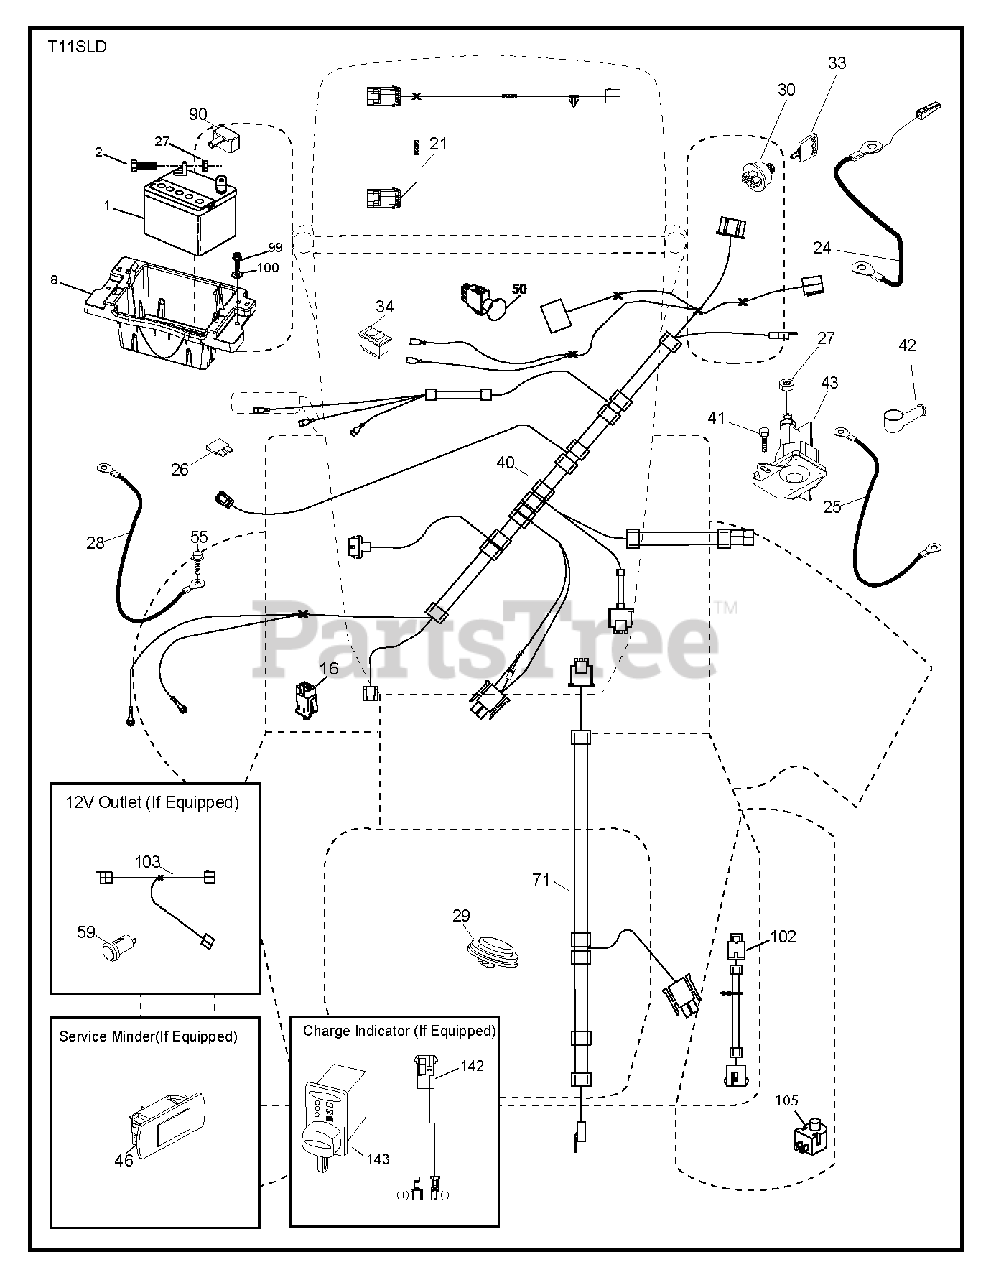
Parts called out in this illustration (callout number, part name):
1	Battery, Dry 30 Amp
2	BOLT.HEX.1/4.X.3/4.DICHROMATE
8	TRAY.BATTERY BOX.FRONT
16	SWITCH INTERLOOK PUSH-IN
21	HARNESS LIGHT ASSY TRACTOR,
24	CABLE.FRBATT.W/WIRE.8GA.8
25	CABLE.BATT.RED.8GA.17
26	FUSE 20AMP
27	NUT
28	CABLE.GROUND.21"BLK.8GA.90T
29	SWITCH.SEAT.DELTA.OPC.
30	SWITCH.IGN.DELTA.W.LGH.ROS
33	KEY.CHAIN.BLISTER.PACK.GEN.USA
40	HARNESS HARNESS..DASH.ING.ELEC
41	SCREW
42	TERMINAL COVER
43	SOLENOID.STARTER.BRASS.PLUNGER
46	GUAGE.SRVCMNDR.HRMTR.
50	SWITCH.PTO.8TERMINAL.STD.BLK
55	SCREW 5/16"
71	HARNESS-CHASSIS SUB
90	COVER.TERMINAL.BATTERY
99	SCREW HEXWSHR 1/4-20X3/4
102	HARNESS PIGTAIL PCH TEX ROS
105	REVERSE SWITCH
